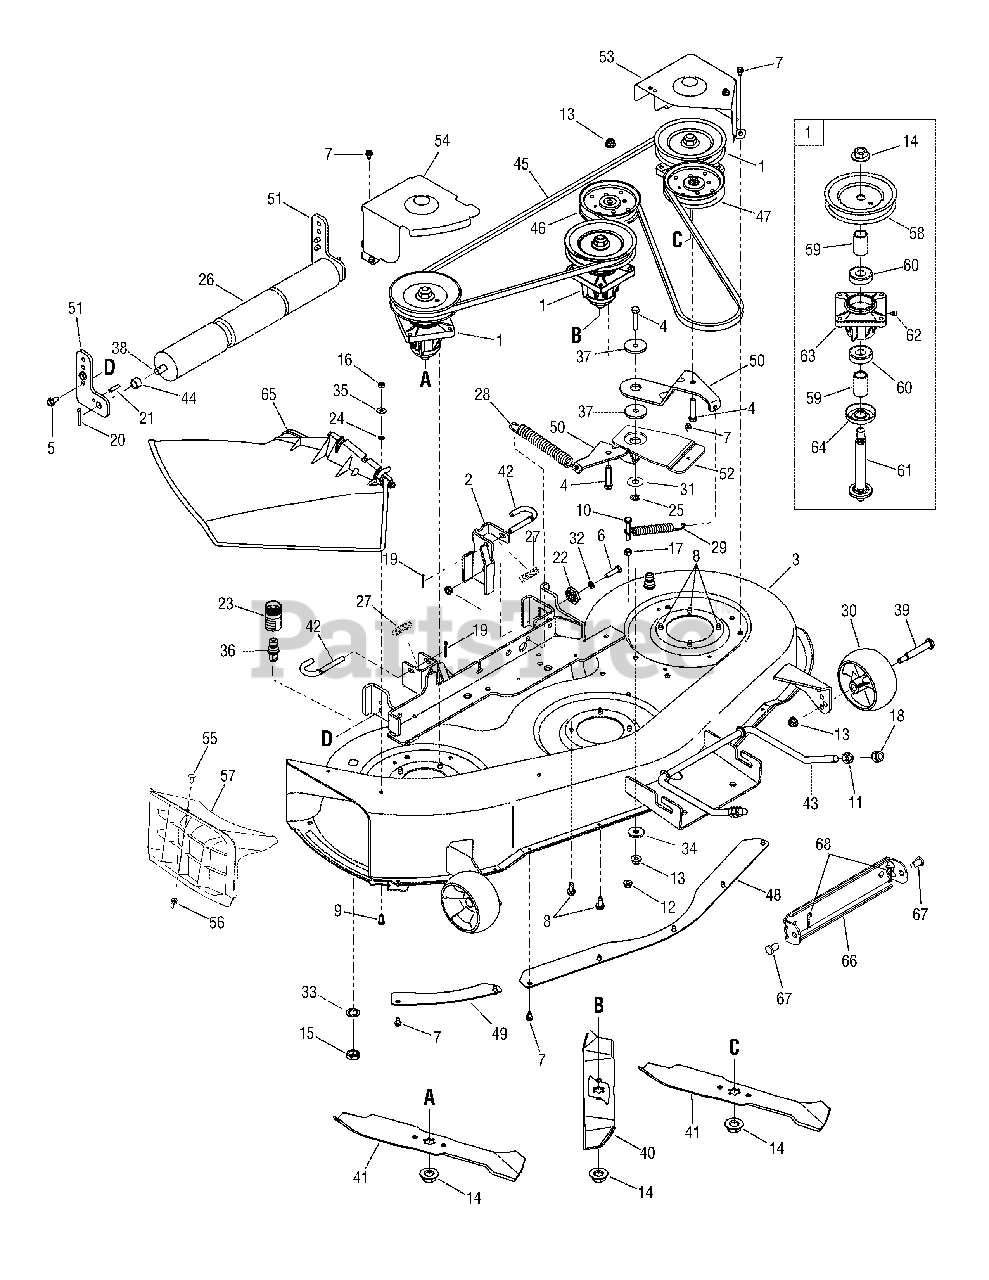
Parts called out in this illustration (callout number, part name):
1	Spindle Assembly
4	Screw, Hex Cap, 3/8-16 x 1.75 Gr5
5	Screw, Hex Wash. Hd. Tapp, 5/16-18 x .75
6	Screw, Hex Cap, 5/16-18 x 1.25 Gr5
7	Screw, Hex Wash. Hd. Tapp, 1/4-20 x .5
8	Screw, Hex Wash. Hd. Tapp, 5/16-18 x .75
9	Screw, Hex Cap, 1/4-20 x .75 Gr5
10	Screw, Hex Cap, 5/16-18 x 2.0 Gr5
11	Nut, Hex, 1/2-13 Gr5
12	Nut, Hex Flange Insert Lock, 5/16-18 GrF
13	Nut, Hex Flange Insert Lock, 3/8-16 GrF
14	Nut, Hex Flange, 5/8-18
15	Nut, Hex, M16-1.5
16	Nut, Hex, 1/4-20 Gr5
17	Nut, Hex, 5/16-18 Gr5
18	Nut, Hex Insert Lock, 1/2013
19	Pin, Cotter, 3/32 x 1.0
20	Pin, Cotter, 5/32 x 1.25
21	Pin, Spring, 1/4 x 1.0
22	Gear, Deck Adjust
23	Adapter, Water Nozzle
24	Nut, Push, .25 x .5
25	Nut, Push On Speed, 3/8 Thrd.
26	Roller, Front
27	Spring, Compression, .531 x 1.75
28	Spring, Extension, .91 x 7.33
29	Spring, Extension, .865 x 4.68
30	Wheel, Deck Ball, 5.0
31	Washer, Flat, .531 x 1.25 x .036
32	Washer, Lock, 5/16
33	Washer, Internal Tooth Lock, 5/8
34	Washer, Flat, .406 x 1.25 x .157 HT
35	Washer, Belleville, .265 x .75 x .062
36	Nozzle, Deck Wash
37	Spacer, Shoulder, .884 x .190
38	Shaft, 1/2 Dia x 20.8
39	Bolt, Shoulder, .496 x 2.5:3/8-16
40	Blade, 3 in 1 Star, 14.88
41	Blade, 3 in 1 Star, 16.28
42	Rod, Deck Release
43	Rod, Deck Front Hanger
44	Spacer, .542 x .75 x .5
45	V-Belt, Type A x 122
46	Pulley, Idler, 4.25 Dia
47	Pulley, Idler, 3.5 Dia.
56	Nut, Wing, 1/4-20
57	Plug, Mulching
58	Pulley, Deck, 5.75 Dia
59	Spacer, .792 x 1.06 x 1.8
60	Bearing, Ball
61	Shaft, Spindle, 6.05 Lg
62	Fitting, Lube
63	Housing, Spindle
64	Shield, Bearing
65	Chute Assembly, Discharge
67	Pin, Clevis, .5 x .78
68	Pin, Internal Cotter
